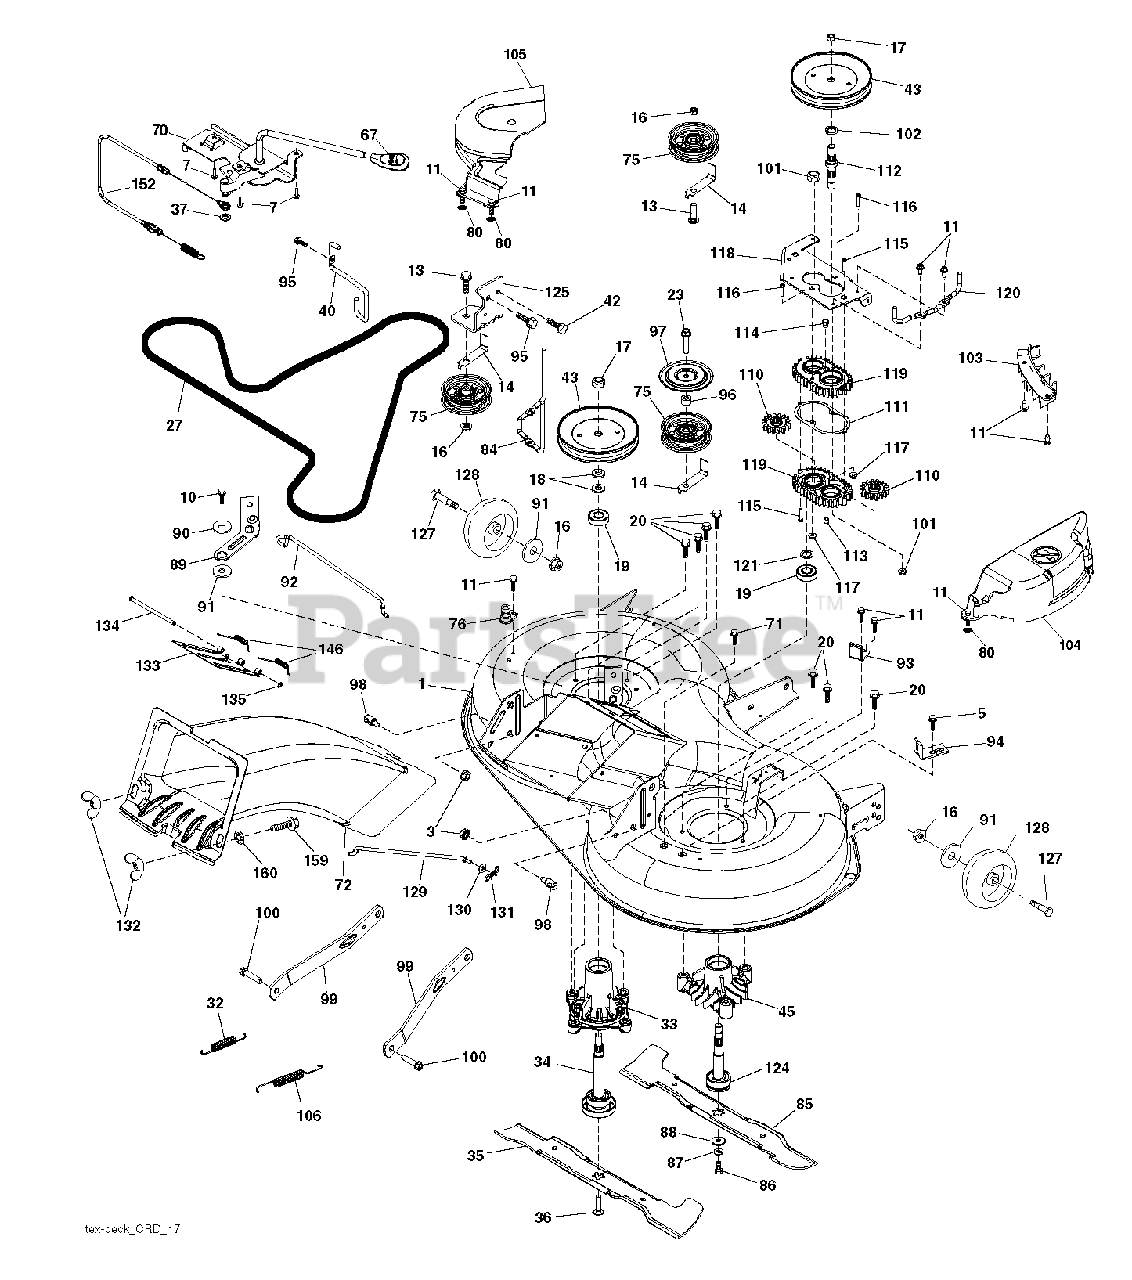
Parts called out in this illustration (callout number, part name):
3	NUT LOCK HEX FLANGE 5/16-18
5	BOLT.5/16HEX.WHS.HD
7	SCREW.#10 X 0.750.BOS THREAD
10	SCREW 3/8-16X1
11	SCREW.1/4-20X5/8
13	BOLT.3/8-16X1.50
14	KEEPER, BELT IDLER
16	NUT LOCK FLG 3/8-16 UNC
17	NUT.FLANGE.LOCK.TOP
18	WASHER.SPACER.MANDREL
20	SCREW, WASHER HEAD
23	SCREW LT
32	SPRING RETURN
33	HOUSING MANDREL
34	SHAFT.ASM.MDRL.N/GREASE.38
35	BLADE.3N1.LH.CRD.97
36	BOLT.WASHER.ASM.7/16-2
40	KEEPER BELT ENGINE LH
42	SCREW
43	PULLEY.MANDREL.5.438.PD
45	HOUSING.MANDREL
67	HANDLE.CLUTCH.CABLE.LT
70	CLUTCH.ASM.MANUAL.YT.PREDATORQ
71	SCREW 3/8-16X1/2
75	FLAT IDLER PULLEY
76	PORT.WASHOUT
80	PALNUT 1/4
84	KEEPER.BELT.MANDREL.PULLEY
85	BLADE.3N1.RH.CRD.97
87	LOCKWASHER
88	WASHER.BLADE
90	SPACER.RETAINER
94	BRKT.CLUTCH.CABLE
95	SCREW, 3/8-16X3/4
98	STUD.FASTNER.W/ANTI-ROTATE
99	ARM.SUSPENSION.MOWER.R
100	BOLT.SHOULDER
102	SPACER BEARING
106	SPRING.BRAKE.RETURN.38"
117	NUT T
127	BOLT.SHOULDER.3/8-16X3-5/8
128	WHEEL. GUAGE RALLY
129	ROD.ANTI.SWAY.48/54"K4
130	WASHER
131	PIN.COTTER.5/16.BOW TI
132	KNOB.HANDLE.3/8.TRI-POINT.BLAC
135	E-RING.5/16"
159	BOLT
